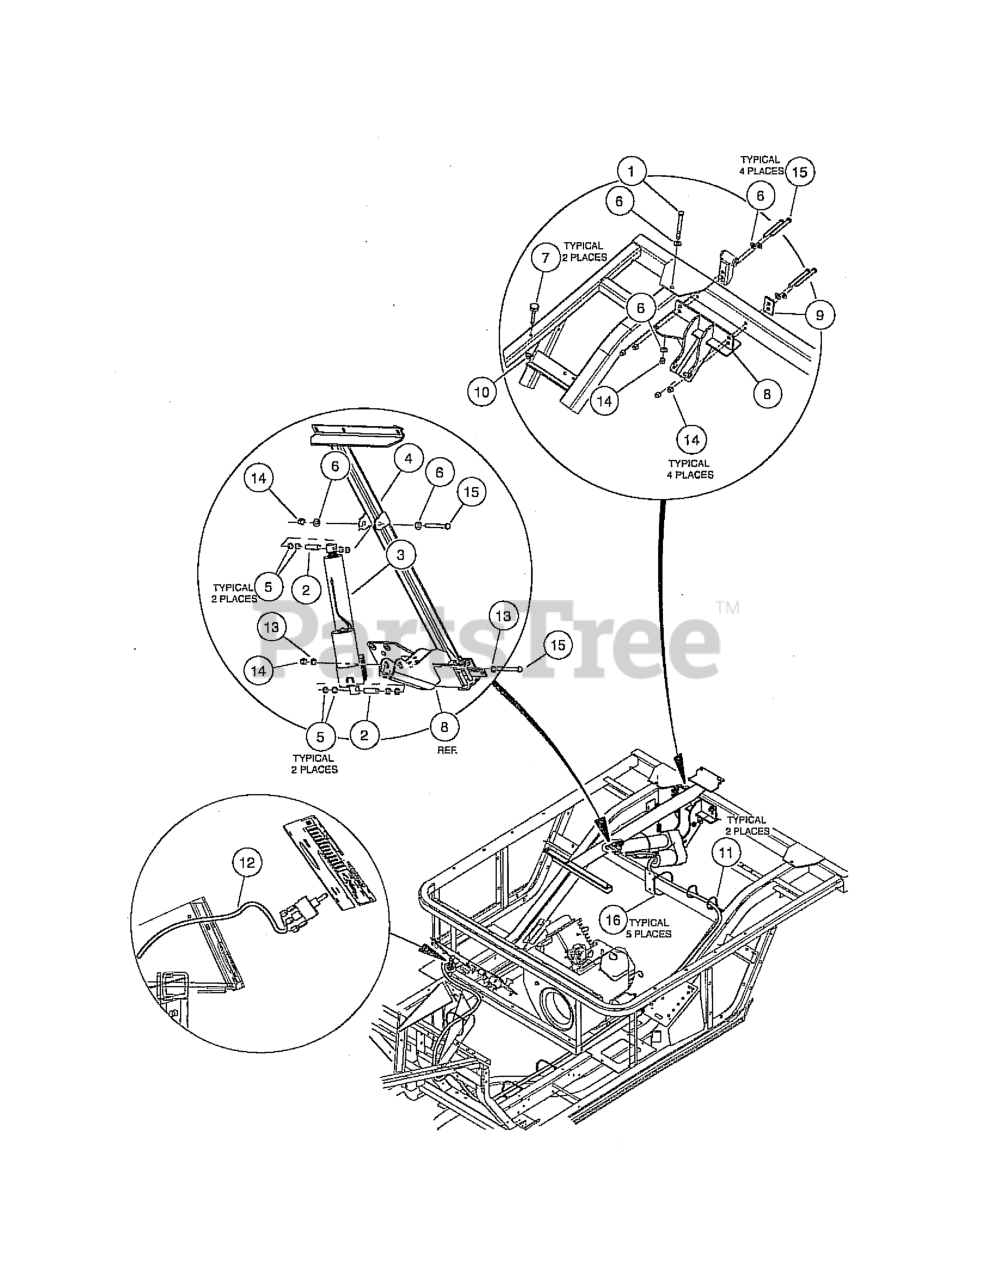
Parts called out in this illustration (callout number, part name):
1	BOLT HEX HEAD
2	BUSHING LONG
3	ACTUATOR ASSEMBLY, ELECTRIC
4	ASM, ACTUATOR ADAPTER
5	BODY SPACER
6	WASHER, 3/8 TYPE B HARD FLAT
7	BUMPER, BED, MTG, FRONT
8	WELDMENT, BRACKET, ACTUATOR
9	PLATE, BACK
10	LOCK NUT, FLG M8 X 1.25 NYLON
11	TIE WRAP, 8.00" WITH MOUNT
12	WIRE HARNESS, ELECTRIC LIFT
13	WASHER,LOCK,HEL SP 3/8 REG
14	LOCKNUT, 3/8-16 HEX
15	SCREW, 3/8-16 X 3.375
16	TIE WRAP, 8" NYLON
